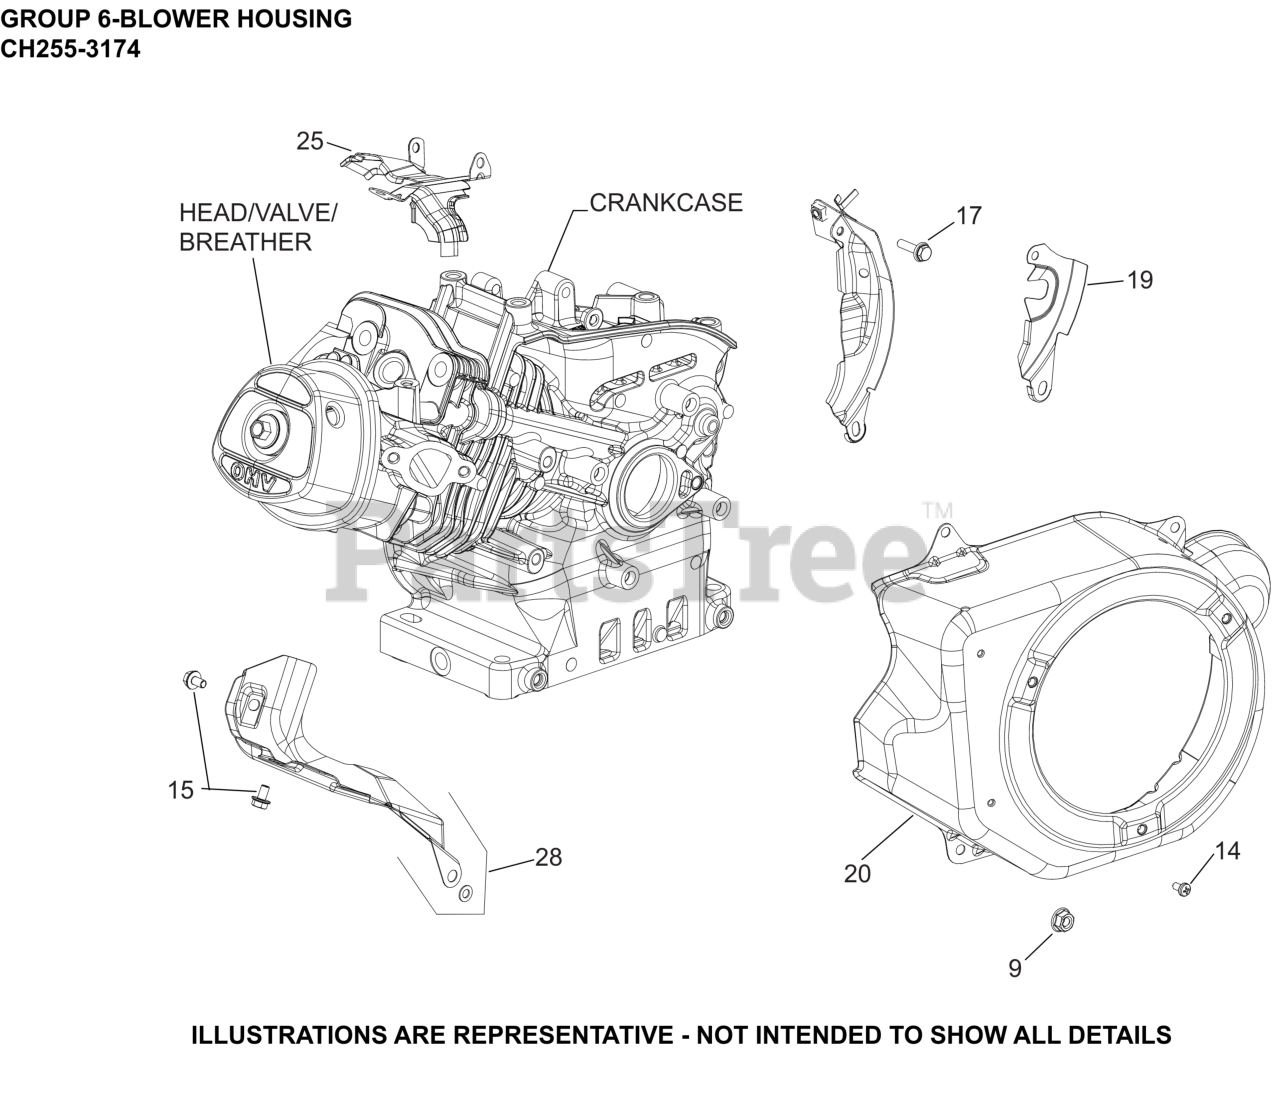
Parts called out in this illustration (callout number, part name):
9	NUT, HEX FLANGE (M6) - USE 14 100 16-S
14	SCREW, COVER TO BLOWER HOUSING
15	SCREW, HEX FLANGE (M6)
17	SCREW, M6 X 22
19	SHIELD, FLYWHEEL ASSEMBLY
20	KIT, BLOWER HOUSING
25	FLOW SHIELD
28	KIT, CYLINDER SHIELD
